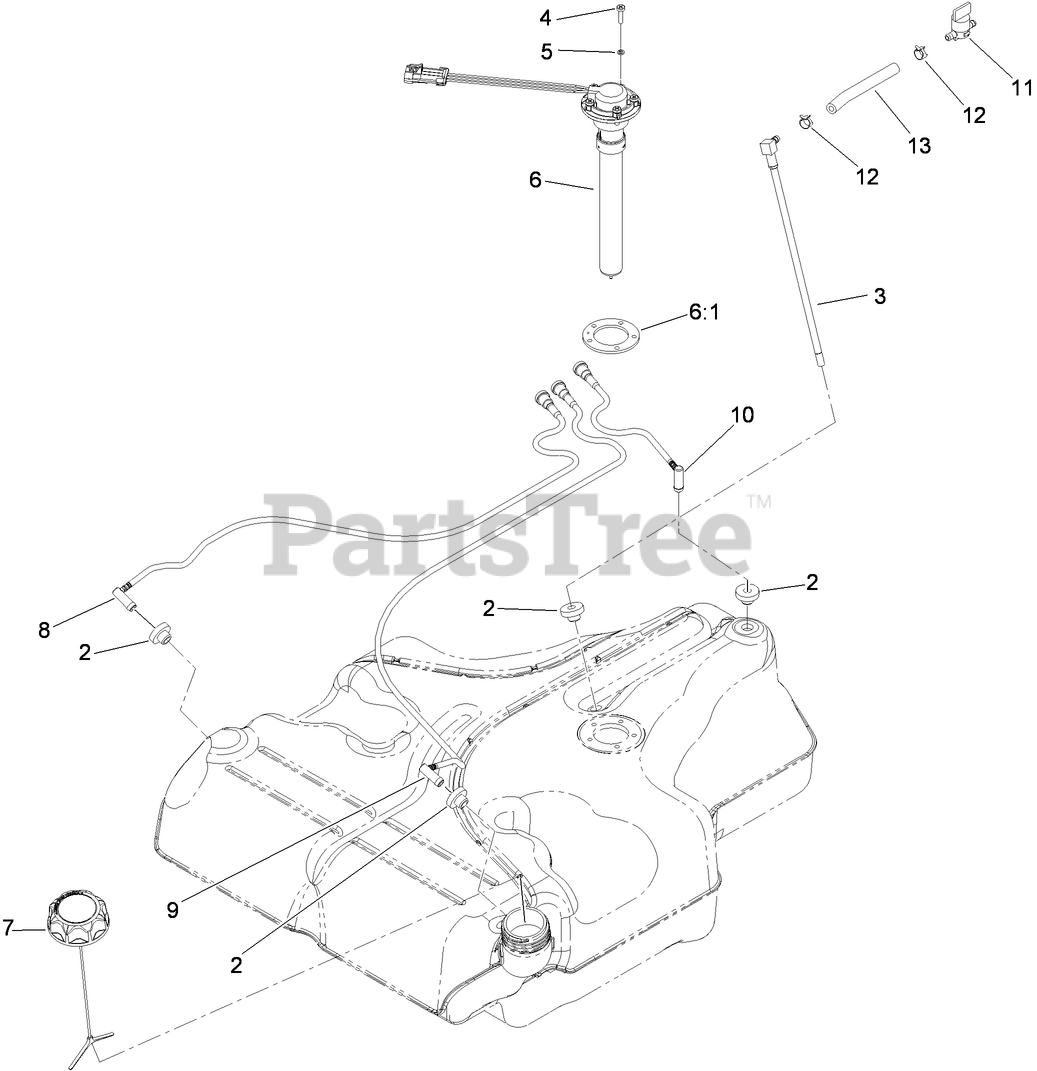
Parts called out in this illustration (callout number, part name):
2	Bushing
3	FITTING-FUEL (W/LINE AND SCREEN)
4	Screw-Pan 10-24 X 3/4
5	Washer-Lock 3/16
6	SENDER-LEVEL, FUEL
6:1	GASKET-SENDER, FUEL
7	CAP-FUEL, RATCHETING
8	TUBE-VENT, RH
9	TUBE-VENT, LH
10	TUBE-VENT, REAR
11	Valve-Fuel
12	Clamp-Hose
13	HOSE-FUEL
